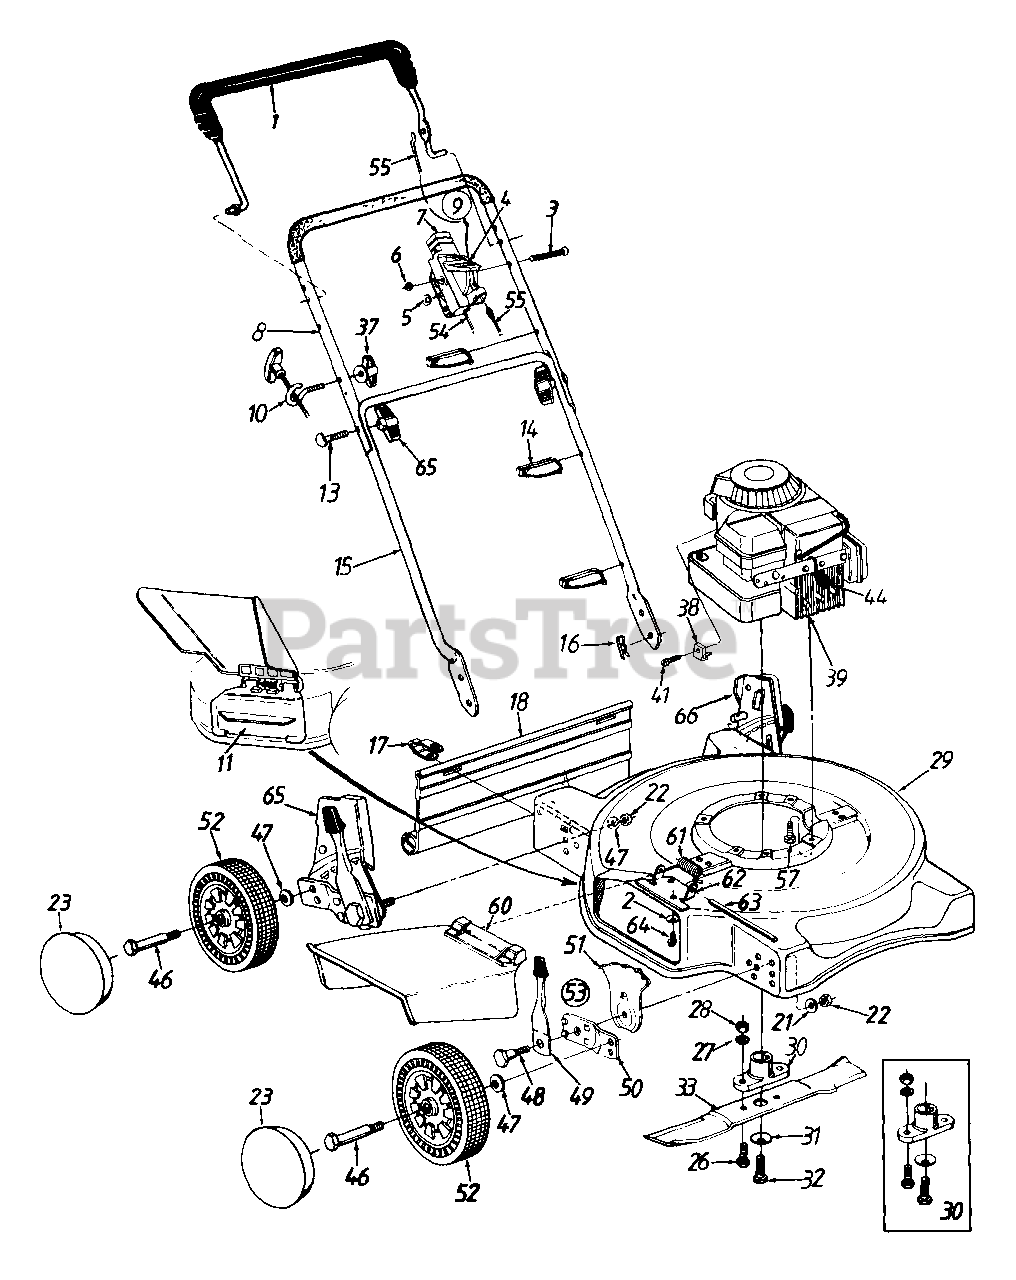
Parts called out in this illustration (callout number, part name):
1	Control Handle Ass'y. w/Plastic
2	Bell-Wash. 1/4" I.D.
3	Oval C-Sunk Mach. Scr.
4	Throttle Lever
5	Spr. Wash..66" I.D.
6	Hex L-Nut 1/4-20 Thd.
7	Throttle Body
10	Rope Guide
11	Mulching Plug
13	Curved Hd. Bolt 5/16-18 x 2" Lg.
14	Cable Tie
16	Hairpin Cotter
17	Hinge Clip
18	Rear Flap
21	Bell-Wash. .39" I.D. x 1.38"
22	Hex Nut 3/8-16 Thd.
23	Hub Caps
26	Hex Bolt 3/8-24 x 1" Lg.
27	L-Wash. 3/8" I.D.
28	Hex Nut 3/8-24 Thd.
31	Bell-Wash. .39" I.D.
32	Hex Bolt 3/8-24 x 1.5" Lg.
33	20" Blade
37	Wing Nut 1/4-20 Thd
38	Cable Clamp
39	Engine
41	Hex Wash. Hd Tap Scr #10-32 x .62" Lg
44	Spark Plug Boot
46	Axle Bolt
47	Bell-Wash .400" I D x 88"
48	Shld. Bolt 50" Dia x .357"
49	Spring Lever Ass'y. w/Knob
51	Height Adj. Plate
52	Wheel Ass'y Comp
53	Height Adj. Ass'y. Comp - R.F.
54	Throttle Cable - 51"
55	Control Cable - 39"
57	Hex L-Wash Hd Scr 3/8-16 x 1.0" Lg.
60	Chute Deflector Ass'y.
61	Torsion Spring
62	Adapter Plate
63	Hinge Pin
64	Hex Self-Tap Scr 1/4-20 x 5"
